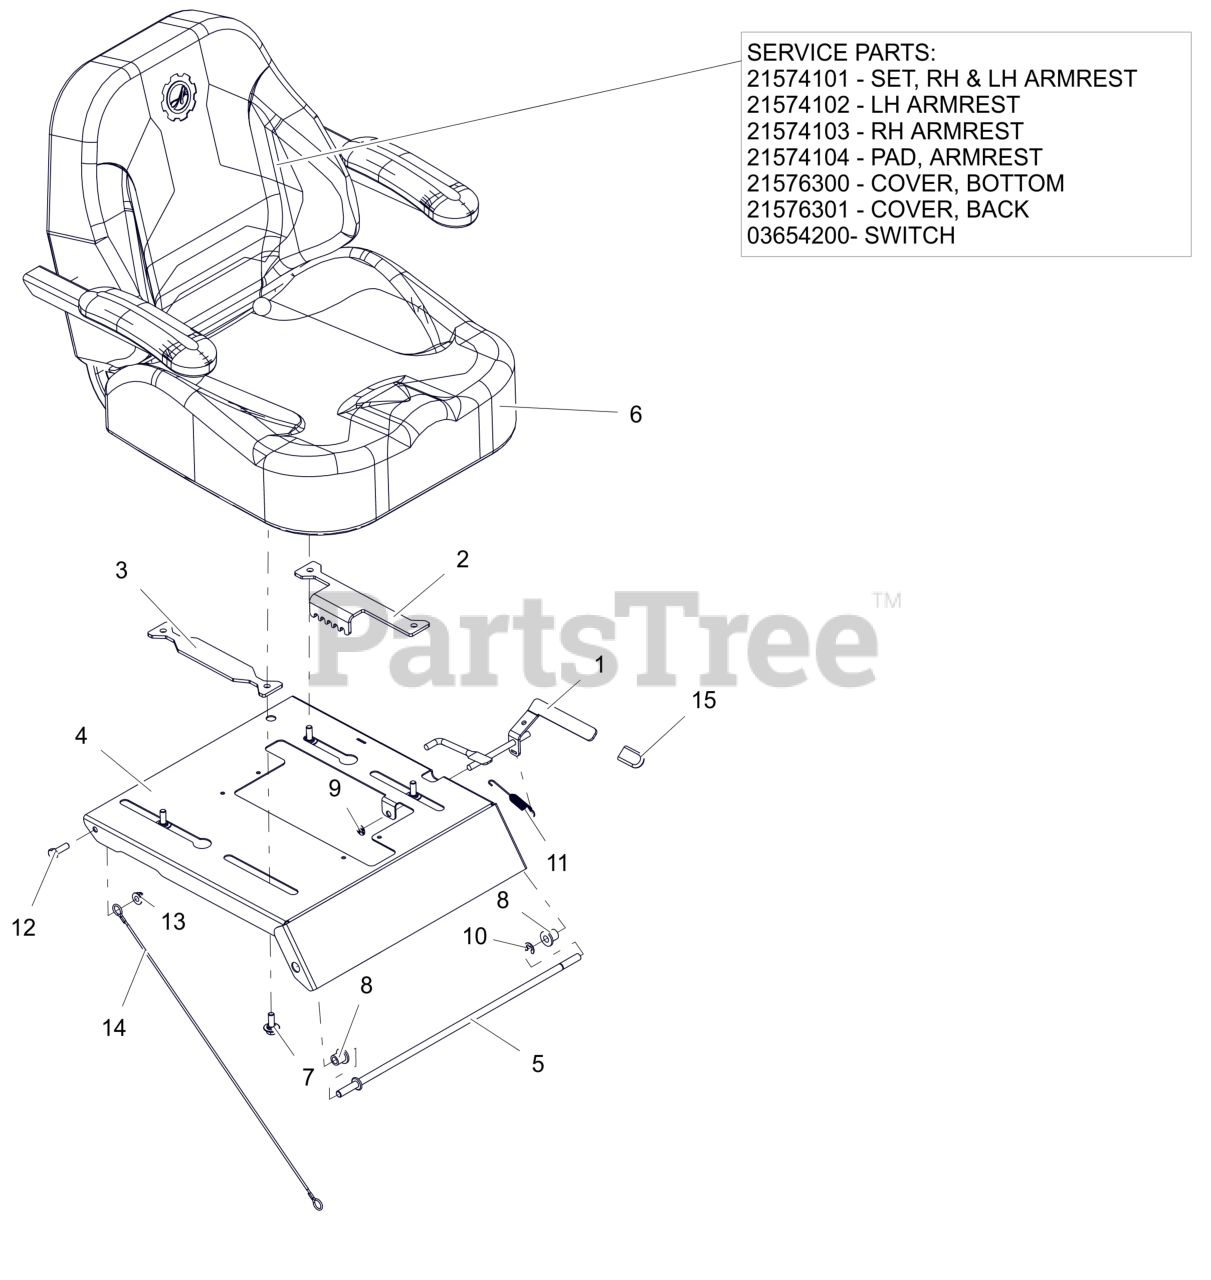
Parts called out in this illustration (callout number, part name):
1	WLDMT, ADJUSTABLE SEAT LATCH
2	PLATE, ADJUSTABLE SEAT TRACK (BLACK)
3	PLATE, ADJUSTABLE SEAT TRACK (BLACK)
4	PLATE, SEAT (ORANGE)
5	ROD- SEAT PIVOT
6	SEAT- IKON XD
6	SET, RH & LH ARMREST
6	LH ARMREST
6	RH ARMREST
6	COVER, BOTTOM
6	COVER, BACK
6	SWITCH- SEAT
7	BLT, SHLDR .31-18 X .100
8	BSHG-FLG .38X.580X.667X.750
9	NUT-PUSH .312
10	RG-RTNG-EXT .375X.035 TYP E
11	SG-TENS .043X.44X3.31 WLD 5.8
12	BLT,HEX .31-18X1.00 G5 ZCC
13	NUT,LK-NYL-FLG .31-18 G5ZC120
14	LANYARD, SEAT CABLE .093X19.5
15	GRIP, SEAT LEVER, GREY
